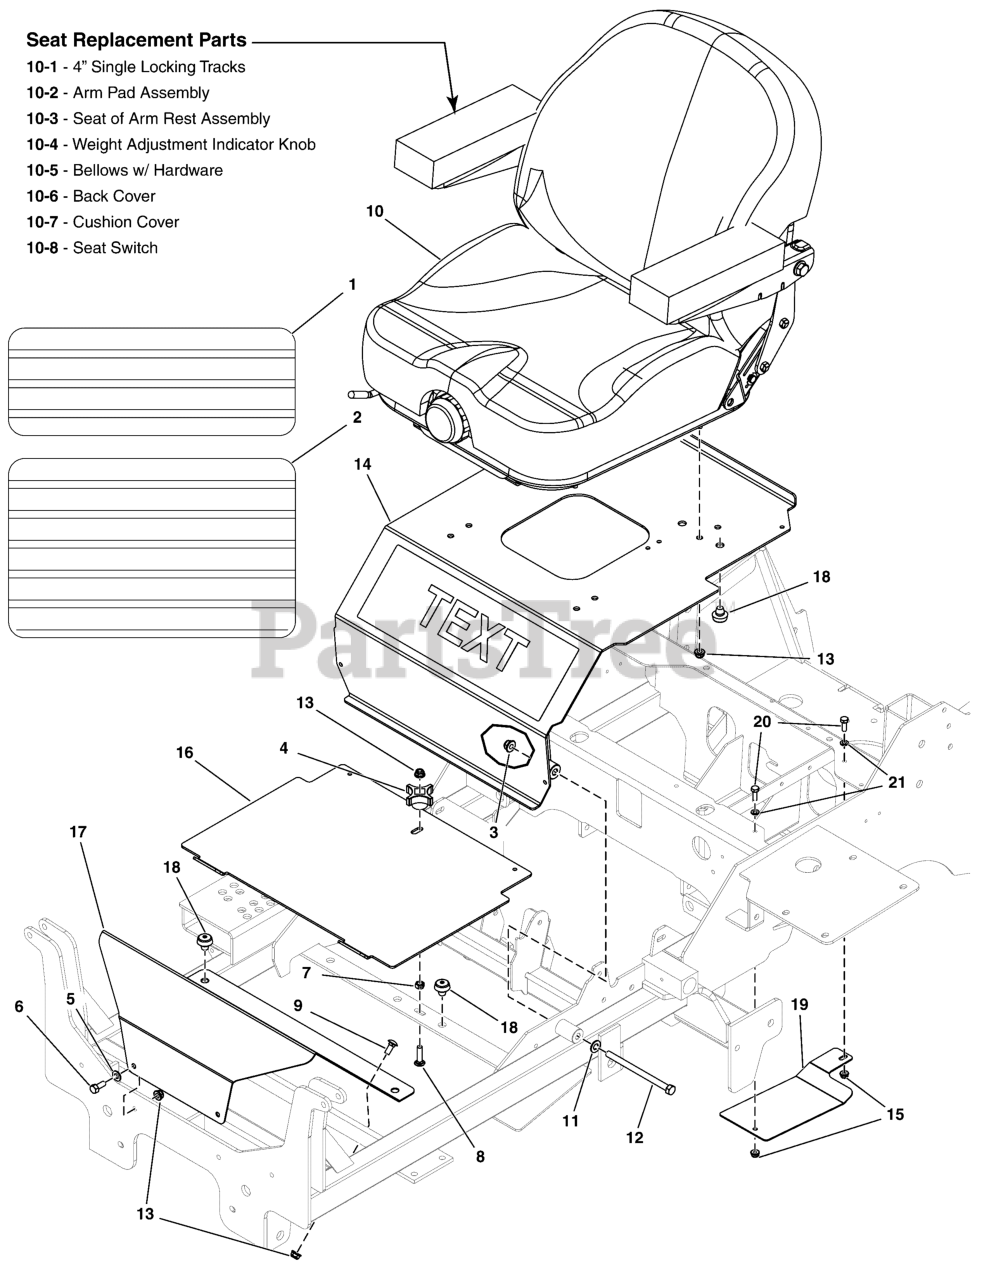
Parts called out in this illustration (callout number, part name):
1	SAFETY WALK, FLOOR REST, 16.00 X 6.00
2	SAFETY WALK, FLOOR PLATE, S50X, 10X17.13
3	NUT, 3/8 - 16 HEX NYLOCK FLANGE
4	KNOB-INT THR .312-18 4-ARM 2.12WD 1.06LG
5	WASHER, 5/16" SAE
6	BOLT, 5/16-18 X 3/4 GD5
7	NUT, 5/16-1/8, HEX, CNTR LK, ZINC PHOS/OIL
8	BOLT, 5/16-18 X 1-1/4, CARRIAGE, GD5, CZ
9	BOLT, 5/16-18 X 3/4, CARRIAGE, GD5, CZ
10	SEAT, MID BACK, SUSP SEAT'SINC, W/SWITCH
10-1	4" SINGLE LOCKING TRACKS BASE
10-2	ARM PAD ASSEMBLY BLK/CHAR CAR FIB/HARBR GRY RED WELT
10-3	SET OF ARMREST ASSEMBLY BLK/CHAR CAR FIB/HARBR GRY RED WELT
10-4	WEIGHT ADJUST INDICATOR KNOB ASSY BASE
10-5	BELLOWS W/ HARDWARE BASE
10-6	BACK COVER FOR FIXED BACK I3M BLK/CHAR CAR FIB/HARBR GRY RED WELT
10-7	CUSHION COVER FOR I3M BLK/CHAR CAR FIB/HARBR GRY RED WELT
10-8	SWITCH, SEAT
11	WASHER, 3/8 SAE
12	BOLT, 3/8-16 X 5-1/2" GD5 CZ
13	NUT, 5/16-18 HEX NYLOCK FLANGE NUT
14	ASSM, SEAT PLATE W/ DECALS, IS2100Z (5411749B)
15	NUT, 1/4-20 HEX SERR. FLANGE
16	PLATE, FLOOR, REMOVABLE, IS700 - RED
17	PLATE, FRONT FLOOR, IS2000Z - RED
18	MNT, VBRTN, RBBR
19	GUARD, DEBRIS, IS2100Z - BLK
20	BOLT, 1/4"-20 X 3/4" GD5 YZ
21	WASHER, 1/4 SAE
